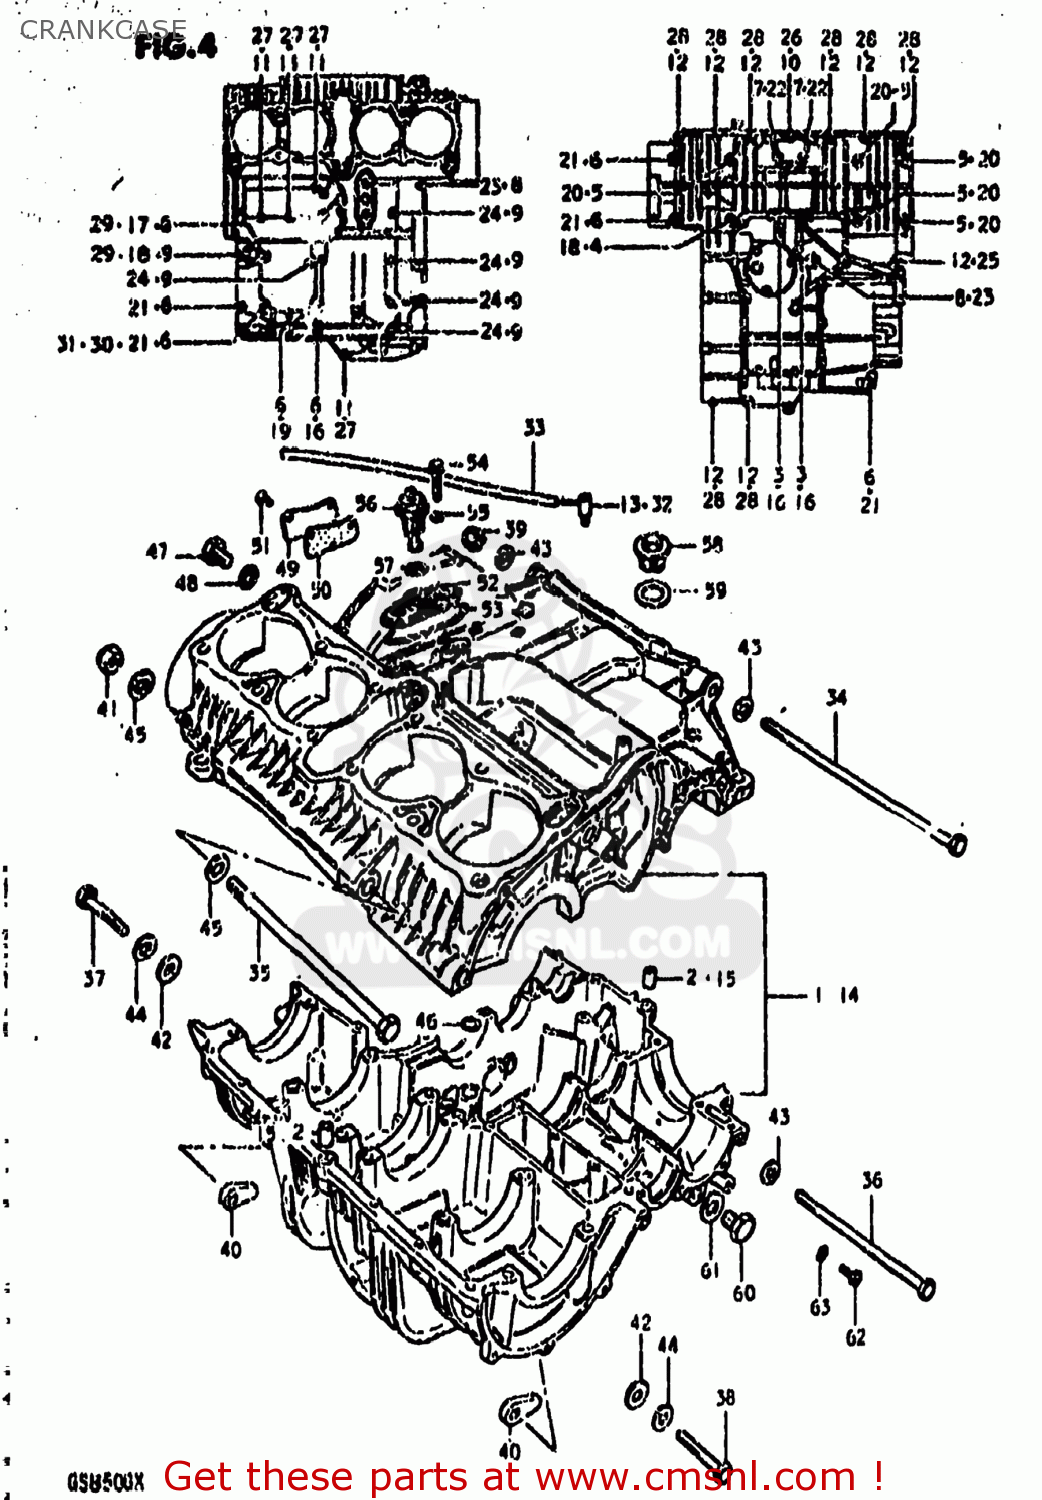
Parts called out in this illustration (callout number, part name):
1	CRANKCASE SET
2	PIN
3	BOLT
4	BOLT
5	BOLT 8X90
6	BOLT 8X65
7	BOLT
8	BOLT (6X90)
9	BOLT (6X75)
10	BOLT ,6X50
11	BOLT,UNDER
12	BOLT 6X35
13	BPLUG,BEVEL GEAR BREATHER
14	CRANKCASE SET
15	PIN
16	BOLT
17	BOLT
18	BOLT
19	BOLT
20	BOLT 8X90
21	BOLT 8X65
22	BOLT
23	BOLT (6X90)
24	BOLT (6X75)
25	BOLT
26	BOLT ,6X50
27	BOLT,UNDER
28	BOLT 6X35
29	NUT
30	NUT
31	GASKET 8.2X14X1 (NAS)
32	BPLUG,BEVEL GEAR BREATHER
33	HOSE
34	BOLT 10X270
35	SHAFT,REAR SWING ARM
36	BOLT(10X165)
37	BOLT 10X60
38	BOLT 10X60
39	NUT
40	NUT
41	NUT 12MM
42	WASHER(10.5X20X3.2)
43	WASHER
44	LOCK WASHER
45	WASHER
46	O RING(D:3.2,ID:12.9)
47	PLUG (14X12)
48	GASKET(14X19.2X2) (NAS)
49	CAP,OIL GALLERY
50	GASKET,OIL GALLERY (MCA)
51	SCREW
52	HOUSING,OIL PRESSURE SWITCH
53	O RING,PRESSURE SWITCH HOUSING
54	BOLT
55	GASKET (NAS)
56	SWITCH ASSEMBLY
57	O RING(D:1.9,ID:18.8)
58	PLUG
59	GASKET (NAS)
60	PLUG
61	GASKET(14X19.2X2) (NAS)
62	SCREW(6X10)
63	GASKET (NAS)
